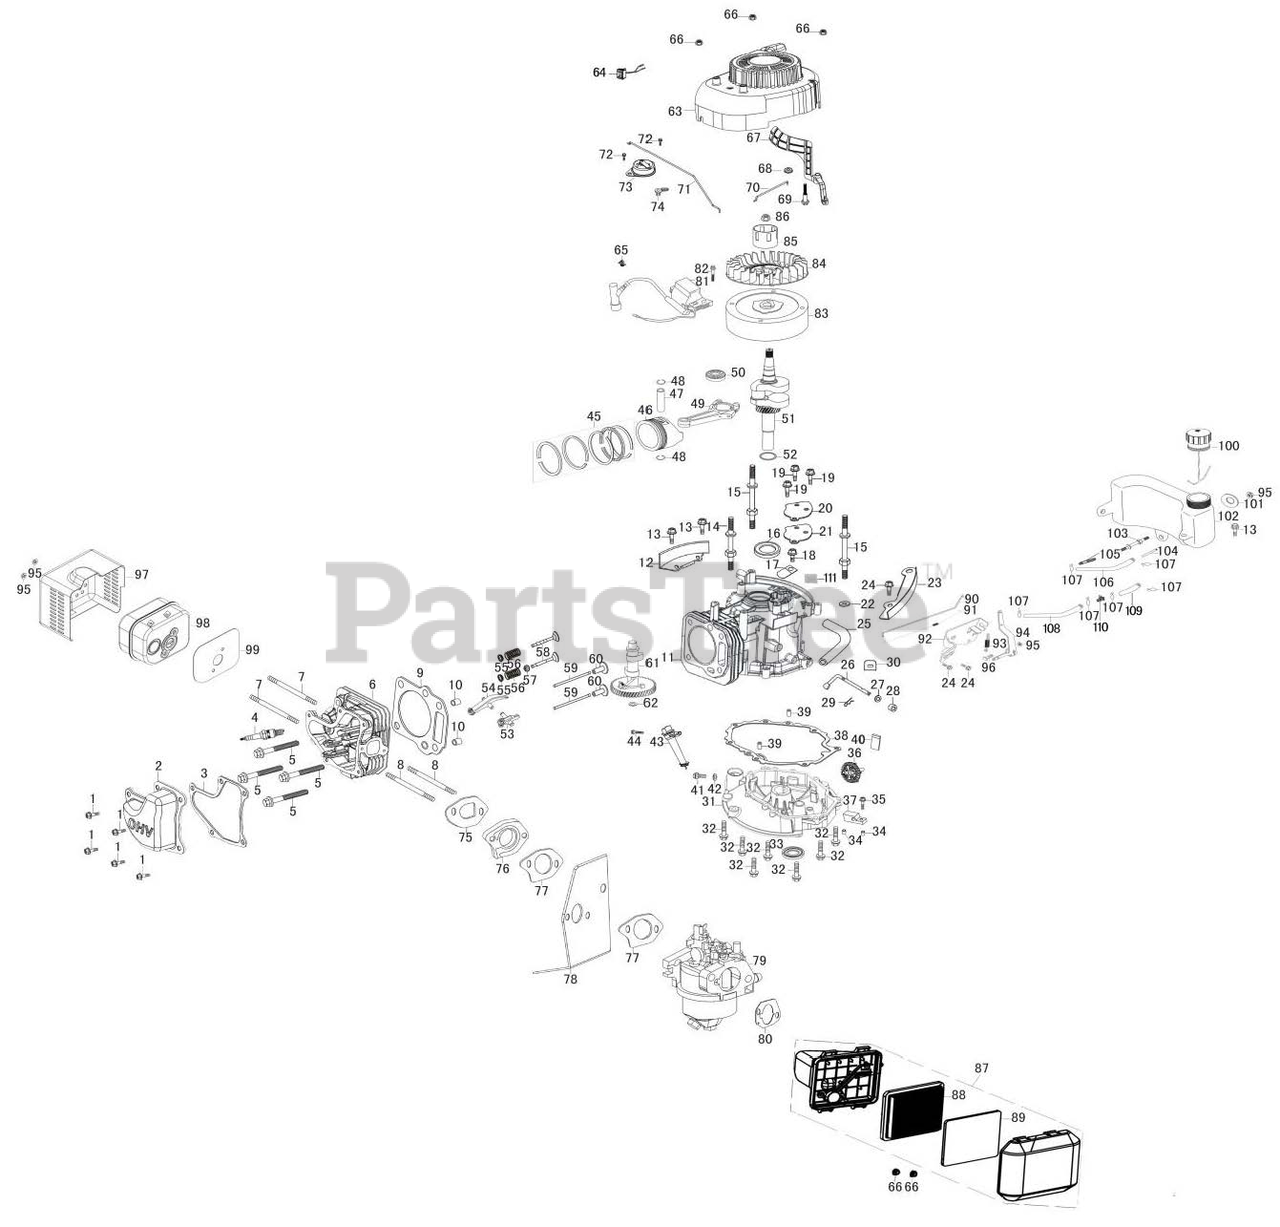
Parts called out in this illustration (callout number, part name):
1	BOLT, CYLINDER HEAD
2	COVER, COMP. HEAD
3	PACKING, HEAD COVER
4	SPARK PLUG, LONCIN 160CC
5	BOLT, CONNECTING ROD
6	HEAD COMP, CYLINDER
7	BOLT, STUD
8	BOLT, STUD
9	GASKET, CYLINDER
10	PIN, DOWEL
11	CRANK CASE
12	SHIELD, TANK SIDE
13	BOLT, FLANGE
14	BOLT, STUD
15	BOLT, STUD
16	OIL SEAL
17	REED VALVE
18	BOLT, FLANGE
19	BOLT,FLANGE
20	CAP,BREATHER CHAMBER
21	PACKING, BREATHER CHAMBER
22	BUSHING
23	SHIELD,TANK SIDE
24	BOLT, FLANGE
25	TUBE,BREATHER
26	SHAFT, GOVERNOR ARM
28	OIL SEAL
29	PIN, LOCK
31	CASE COVER
32	BOLT, FLANGE
33	OIL SEAL
34	PIN, DOWEL
35	BOLT, FLANGE
36	GOVERNOR COMP
37	PLATE, GOVERNOR HOLDER
38	PACKING,CASE COVER
39	PIN, DOWEL
40	RUBBER, OIL DEFLECTOR
41	BOLT, DRAIN PLUG
43	CAP ASS'Y
44	BOLT, FLANGE
45	RING SET
47	PIN.PISTON
48	CLIP,PISTON PIN
49	ROD ASSY.,CONNECTING
50	EDDP GROOVE BALL BEARING
51	CRANKSHAFT COMP
53	ARM, VALVE ROCKER
54	ARM, VALVE ROCKER
55	RETAINER, VALVE SPRING
56	SPRING, VALVE
57	SEAL, VALVE STEM
58	VALVE ASSY.
59	ROD,PUSH
61	CAMSHAFT ASSY.
63	STARTER SUBASSEMBIY
64	SWITCH ASSY.,ENGINE STOP
65	LOCATION CABLE CLIP
66	NUT, FLANGE
67	LAMINA, CONTROL THROTTLE
68	DUST COVER
69	BOLT, FLANGE
70	ROD,THROTTLE
71	ROD,THROTTLE
72	BOLT, FLANGE
73	ASS'Y, CONTROL THROTTLE
74	LOCKER, CHOKE VALVE PULL ROD
75	PACKING, INSULATOR
76	INSULATOR, CARBURETOR
77	PACKING, CARBURETOR
78	INSULATOR, CARBURETOR
79	CARBURETOR
80	GASKET, AIR CLEANER
81	COIL ASS'Y, IGNITION
82	BOLT, FLANGE
83	FLYWHEEL COMP
84	FAN, COOLING
85	PULLEY, STARTER
86	NUT, SPECIAL
87	AIR CLEANER ASS'Y
88	FILTER, AIR - LONCIN 160CC
89	ELEMENT, AIR CLEANER
90	ROD,GOVERNOR
91	SPRING,THROTTLE RETURN
92	LIFTER, VALVE
93	SPRING, GOVERNOR
94	ARM,GOVERNOR
95	NUT, FLANGE
96	BOLT, GOVERNOR ARM
97	PROTECTOR COVER, MUFFLER
98	MUFFLER ASS'Y
99	GASKET, MUFFLER
100	CAP, FUEL - SVC
102	TANK COMP.,FUEL
103	BOLT, STUD
104	STRAINER, FUEL
105	CABLE CLEAT
107	LOOP, TUBE
108	TUBE,FUEL
109	TUBE,FUEL
110	COCK ASSY.,FUEL
111	OIL STRAINER
